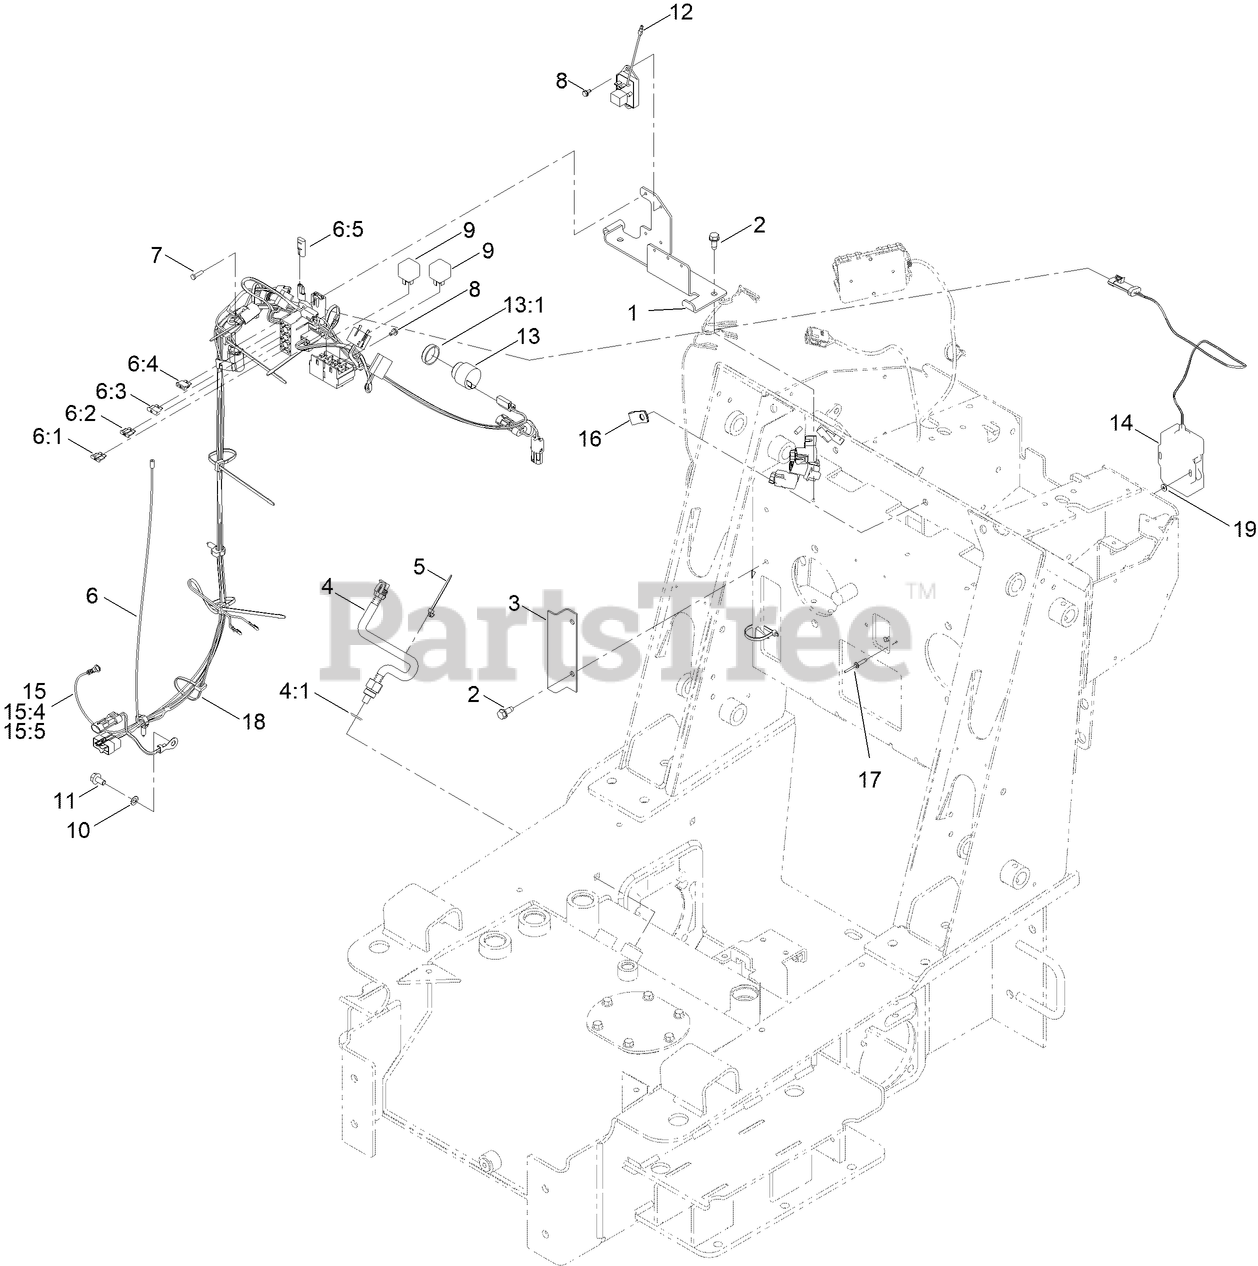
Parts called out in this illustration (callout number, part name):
1	BRACKET-FUSE/RELAY
2	SCREW-THD ROLL, HWH
3	SHIELD-WIRING
4	SWITCH-TEMPERATURE
4:1	O-RING
5	TIE-CABLE
6	HARNESS-WIRE
6:1	FUSE-BLADE, 30 AMP
6:2	FUSE-BLADE, 25 AMP
6:3	FUSE-BLADE, 10 AMP
6:4	FUSE-BLADE, 15 AMP
6:5	CAP-PLUG
7	SCREW
8	SCREW-HWH
9	RELAY
10	WASHER-LOCK
11	SCREW-HHF
12	MODULE-IGNITION DELAY
13	AUDIO ALARM ASM
13:1	NUT-PLASTIC, KNURLED
14	GPS ASM
15	HARNESS-WIRE, GPS
15:4	FUSE-MINI BLADE, 5 AMP
15:5	COVER-FUSE, SINGLE
16	CLAMP-R
17	RIVET-POP
18	TIE-CABLE
19	WASHER-PLAIN
